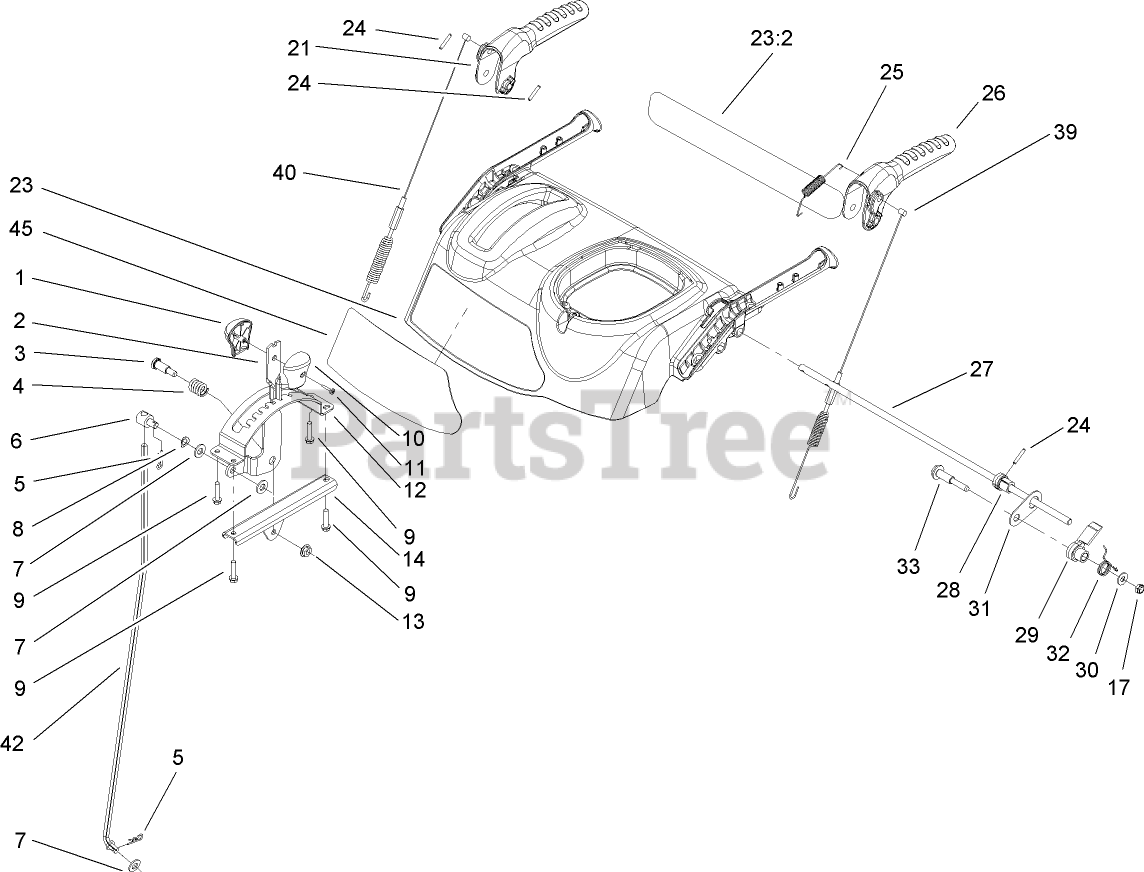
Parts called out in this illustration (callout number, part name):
1	KNOB-SHIFT, RH
2	SELECTOR-SPEED
3	SCREW-SHOULDER
6	TRUNNION
7	WASHER-FLAT
8	WASHER-SPRING
9	SCREW-PLASTITE
10	KNOB-SHIFT, LH
11	SCREW-PPH
12	GUIDE-SELECTOR, SPEED
13	NUT-HF
14	MOUNT-SELECTOR, SPEED
17	NUT-LOCK, NI
21	LEVER-AUGER
23	CONTROL PANEL ASM
23:2	DECAL-CONTROL PANEL
24	PIN-SPRING
25	SPRING-TENSION
26	LEVER-TRACTION
27	ROD-LOCKOUT
28	CAM-LOCKOUT
29	LATCH-LOCKOUT
30	WASHER-FLAT
31	LINK-LOCKOUT
32	SPRING-TORSION
